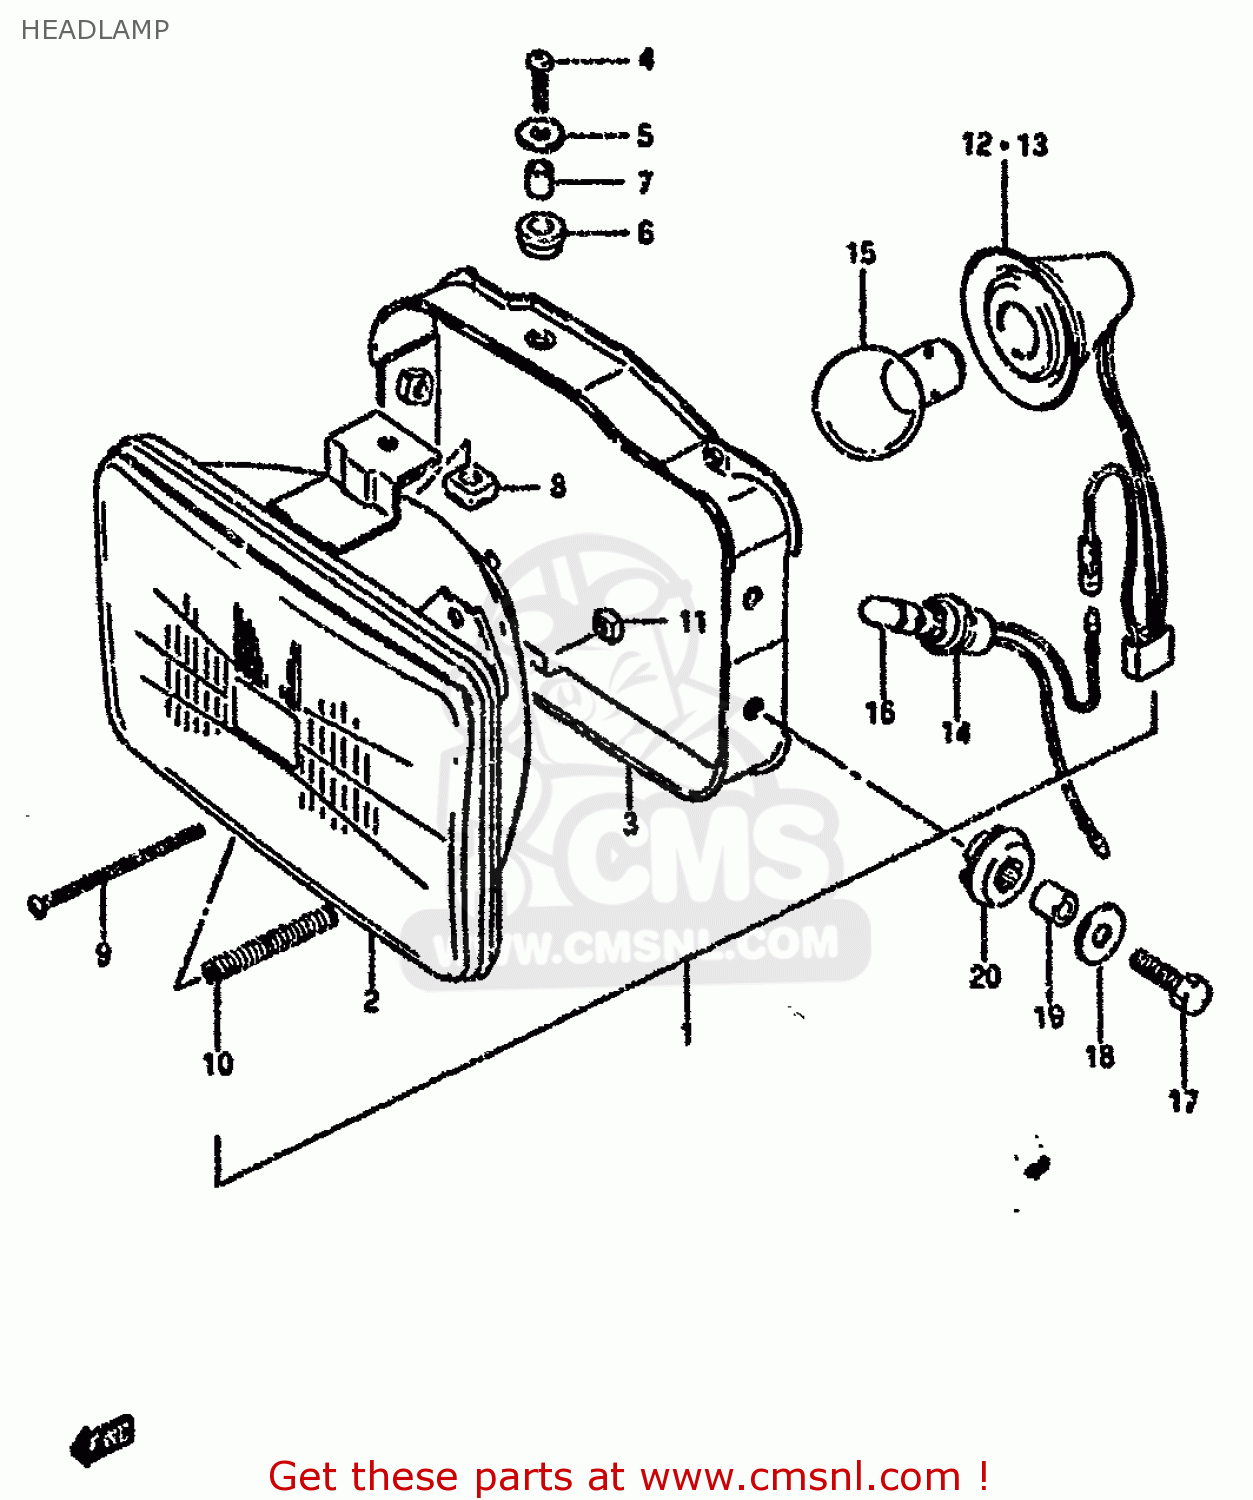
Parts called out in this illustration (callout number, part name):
1	HEADLAMP ASSY
2	UNIT
3	HOUSING
4	SCREW(5X14)
5	WASHER
6	CUSHION
7	SPACER
8	NUT
9	SCREW,HEADLAMP ADJUST
10	SPRING
11	NUT
12	SOCKET
13	SOCKET,HEAD LAMP
14	SOCKET,PARKING
15	BULB
16	BULB(12V4W)
17	BOLT
18	WASHER (6.5X20X1.2)
19	SPACER (6.8X10X10)
20	CUSHION
